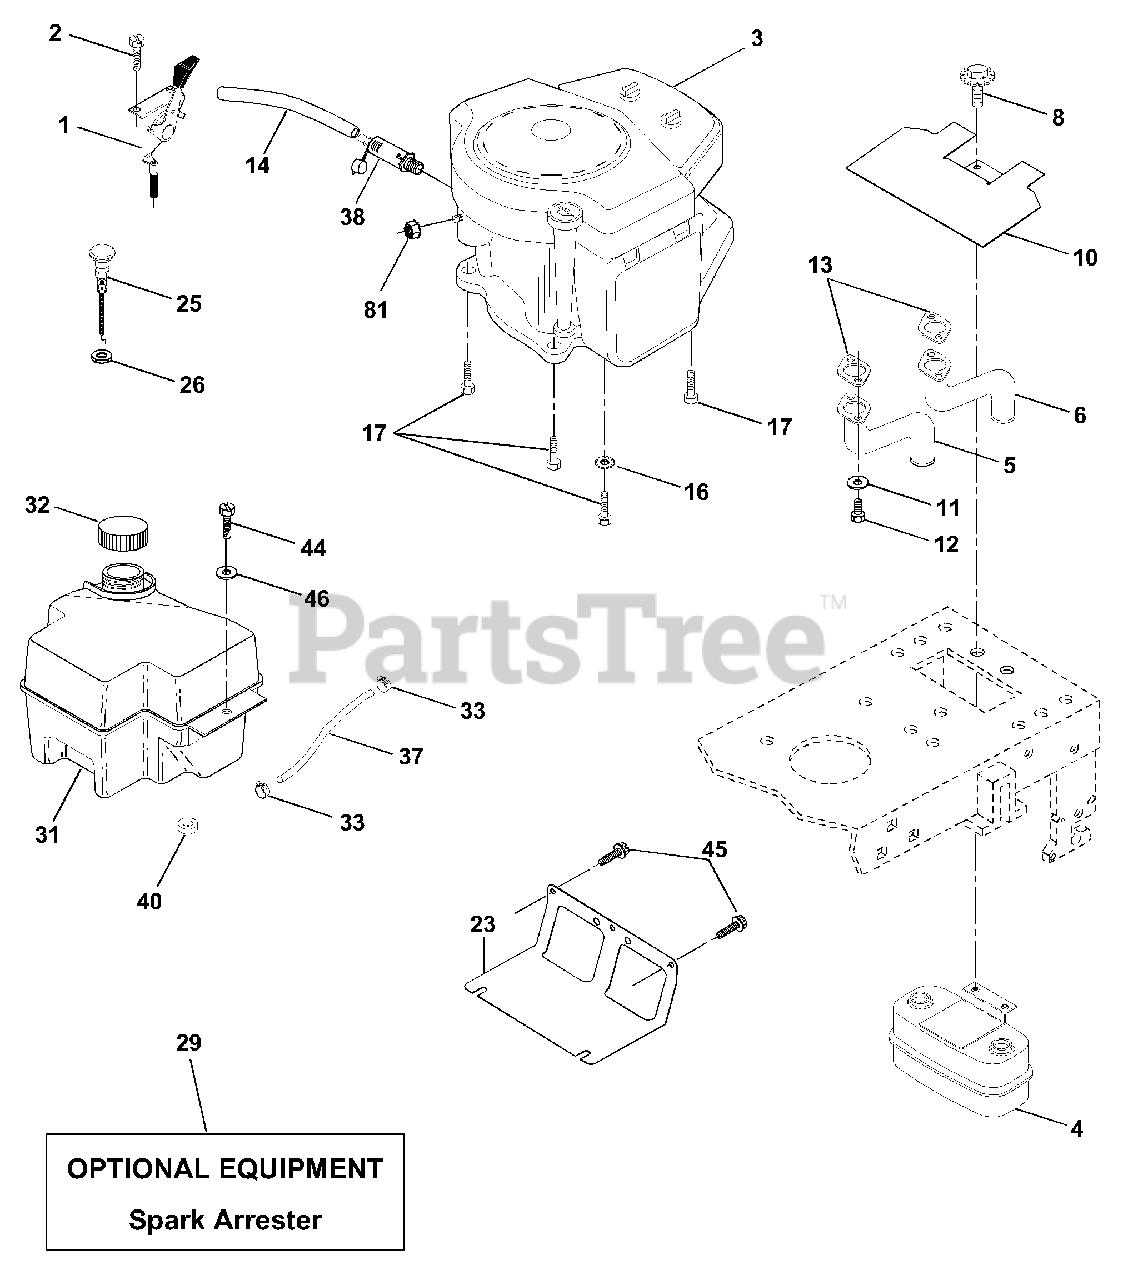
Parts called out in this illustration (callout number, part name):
1	Control Throt
2	Screw Hex Thd Cut 1/4-20x5/8 T
4	Muffler Exhaust
5	Exhaust Asm. Lh
6	Exhaust Asm. Rh
8	Bolt 5/16-18unc x 3/4 w/sems
10	Heat Shield Lt
11	Washer Lock Hvy. Helical 1/4
12	Screw Hex Hd Cap 5/16-18 x 3/4
13	Gasket Muffler
14	Tube Drain Oil Easy
16	Washer Lock Ext Tooth 3/8
17	Screw Thdrol 3/8-16 x 1-1/2 Tytt
23	Shield BRN/DBR Guard
25	Control Choke
26	Nut Keps 3/8-24 UNF
29	Arrestor Spark
31	Tank Fuel
32	Cap Fuel
33	Clamp Hose Blk
37	Line Fuel
38	Plug Drain Oil Easy
40	Bushing Snap Nyl Black
44	Screw Hexwsh Thdrol 1/4-20 x 3/4
45	Screw Hex wsh Thdrol 3/8-16 x 3/4
46	Washer 9/32 x 7/8 x 16 Ga.
81	Nut Keps Hex 1/4-20 unc
